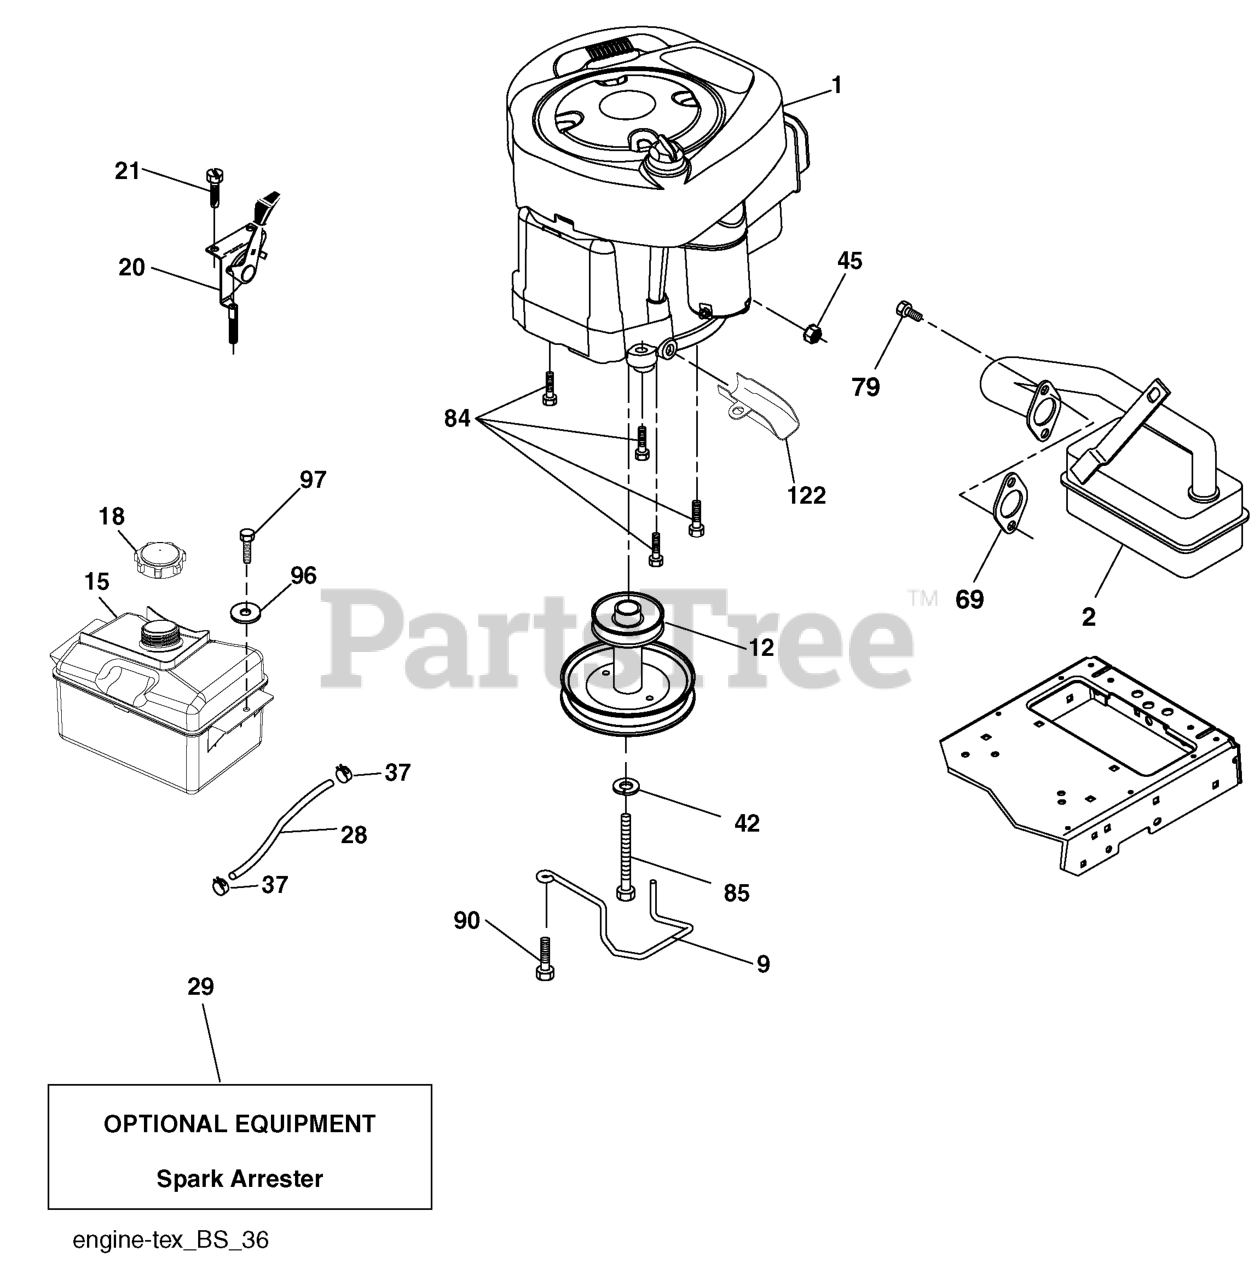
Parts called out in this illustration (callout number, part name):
2	MUFFLER.LT.BRIGGS.14HP.IC/OHV
9	KEEPER.BELT.ENGINE.4.2
12	PULLY ENGINE
15	RP TANK FUEL FRT 1.5 GAL
18	CAP ASM.FUEL.2.25"FR.
20	CONTROL.TH/CK.C.
21	SCREW.#10 X 0.750.BOS
28	LINE.FUEL.20"FRONT.EMI
29	KIT.SPARK ARRESTOR 794945 B&S
37	HOSE CLAMP
42	LOCKWASHER
45	NUT
69	REPL BY 532 27 22-93
79	SCREW.SOCKET HD.5/16-1
84	SCREW.3/8-16
85	BOLT HEX 7/16-20X4-1/4"
90	SCREW 3/8-16X1
96	WASHER
97	SCREW HEXWSHR 1/4-20X3/4
122	EXTENSION DRAIN OIL
